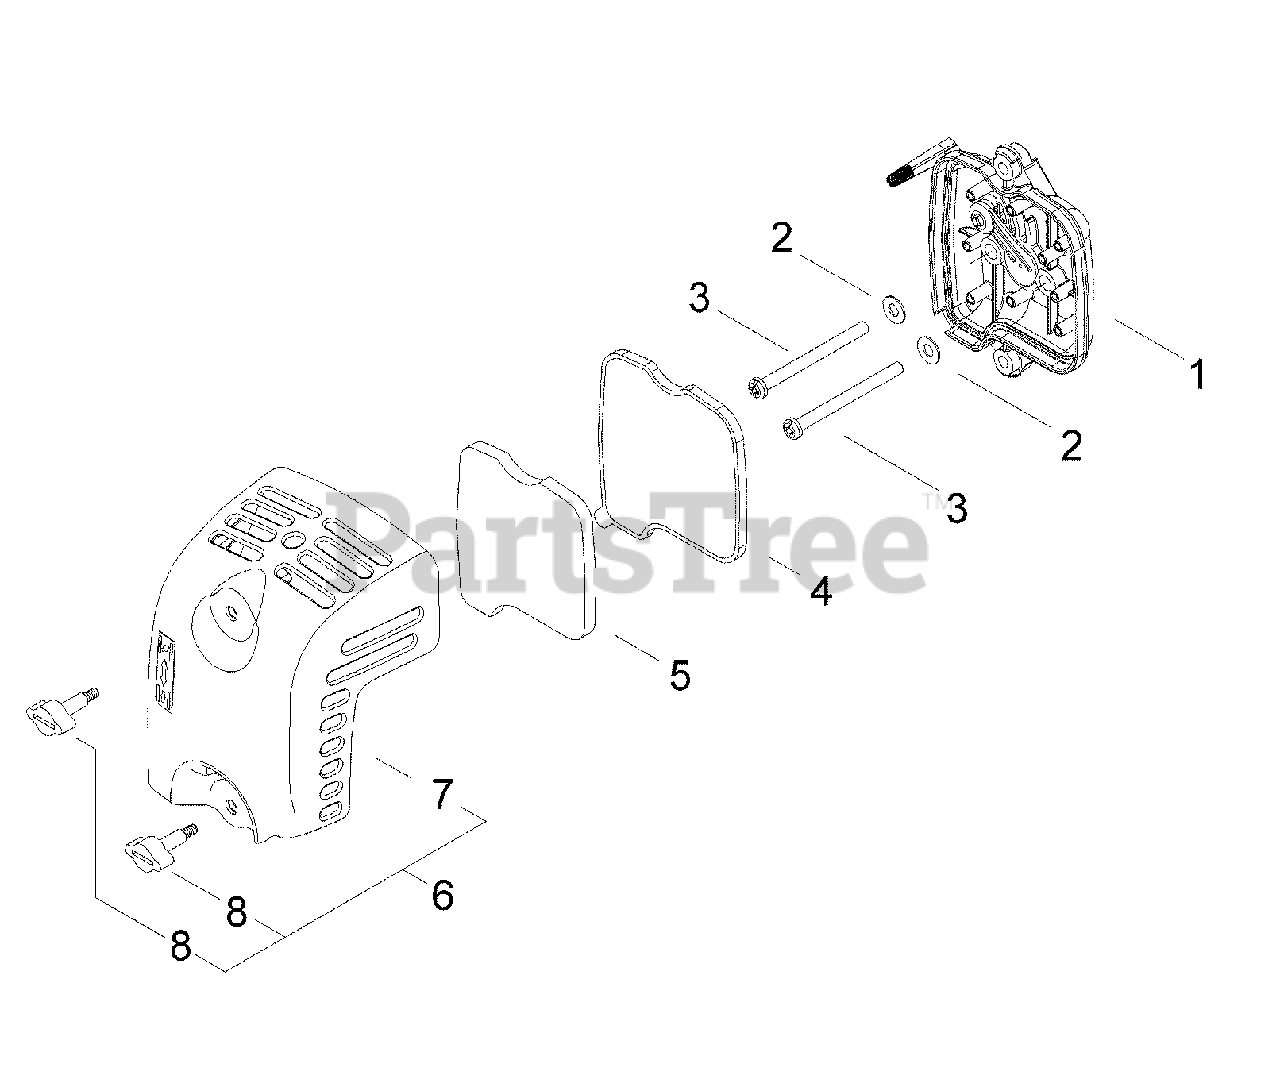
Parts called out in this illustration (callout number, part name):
1	CASE, AIR FILTER
2	WASHER - 5
3	SCREW - 5X60
4	FILTER, AIR
5	PRE-FILTER - FOAM
6	AIR FILTER COVER ASSY
7	COVER, AIR FILTER
8	THUMBSCREW
